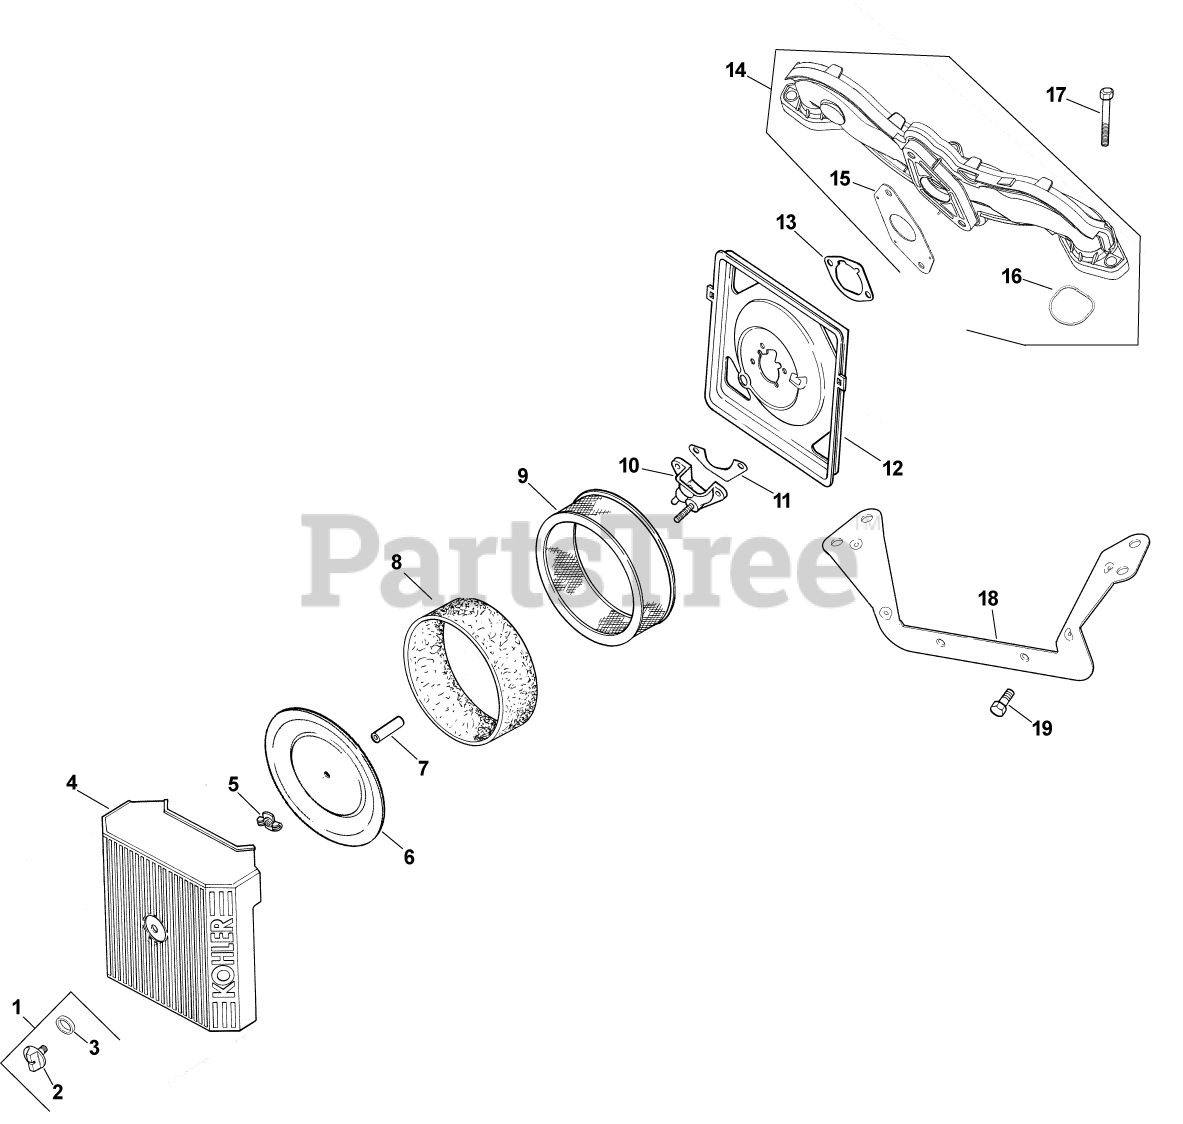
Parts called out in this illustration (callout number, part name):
1	KIT, KNOB W/SEAL
2	KNOB, COVER
4	COVER, AIR CLEANER
5	NUT, WING
6	COVER, INNER AIR CLEANER
7	SEAL, BREATHER
8	PRE-CLEANER (HIGH)
9	ELEMENT, AIR CLEANER - Also available Retail Packaged 47 883 03-S1 Air Filter Kit
10	CUP, FUEL SPITBACK W/NIPPLE
11	GASKET, FUEL SPITBACK CUP
12	BASE, AIR CLEANER-USE 24 094 82-S
13	GASKET, AIR CLEANER BASE
14	MANIFOLD, INTAKE - PLASTIC-USE 24 164 91
15	O-RING, INTAKE PORT
16	GASKET, CARBURETOR
17	SCREW, FLG M6X1.0X40
18	BRACKET, AIR CLEANER BASE
19	SCREW, FLG THD FRM M5X.8X10
